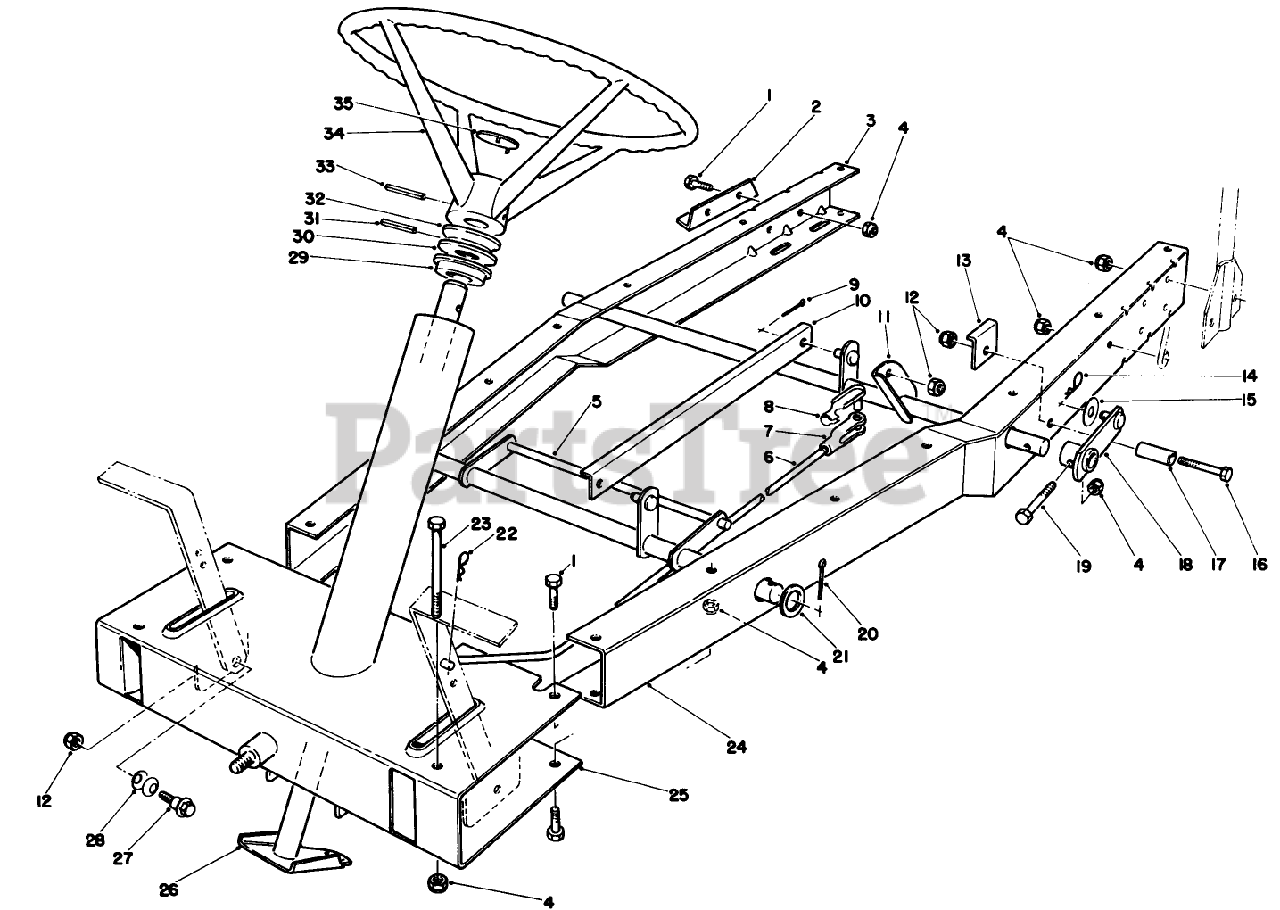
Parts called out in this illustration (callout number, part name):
1	SCREW-HH
4	NUT-LOCK, NI
6	ROD-CLUTCH
7	CLEVIS-ADJ
8	CLEVIS PIN ASM
9	PIN-COTTER
12	NUT-LOCK, NI
14	PIN-HAIR
15	WASHER
16	SCREW-HH
17	SPACER-STOP,DECK
20	PIN-COTTER
21	WASHER-FLAT
22	PIN-COTTER
23	SCREW-HH
27	BOLT-SHOULDER
28	WASHER-BELLEVILLE
30	WASHER-STEERING
31	PIN-ROLL
32	SPACER-STEERING
33	PIN-ROLL
34	STEERING WHEEL ASM
35	INSERT-STEERING WHEEL, TORO
